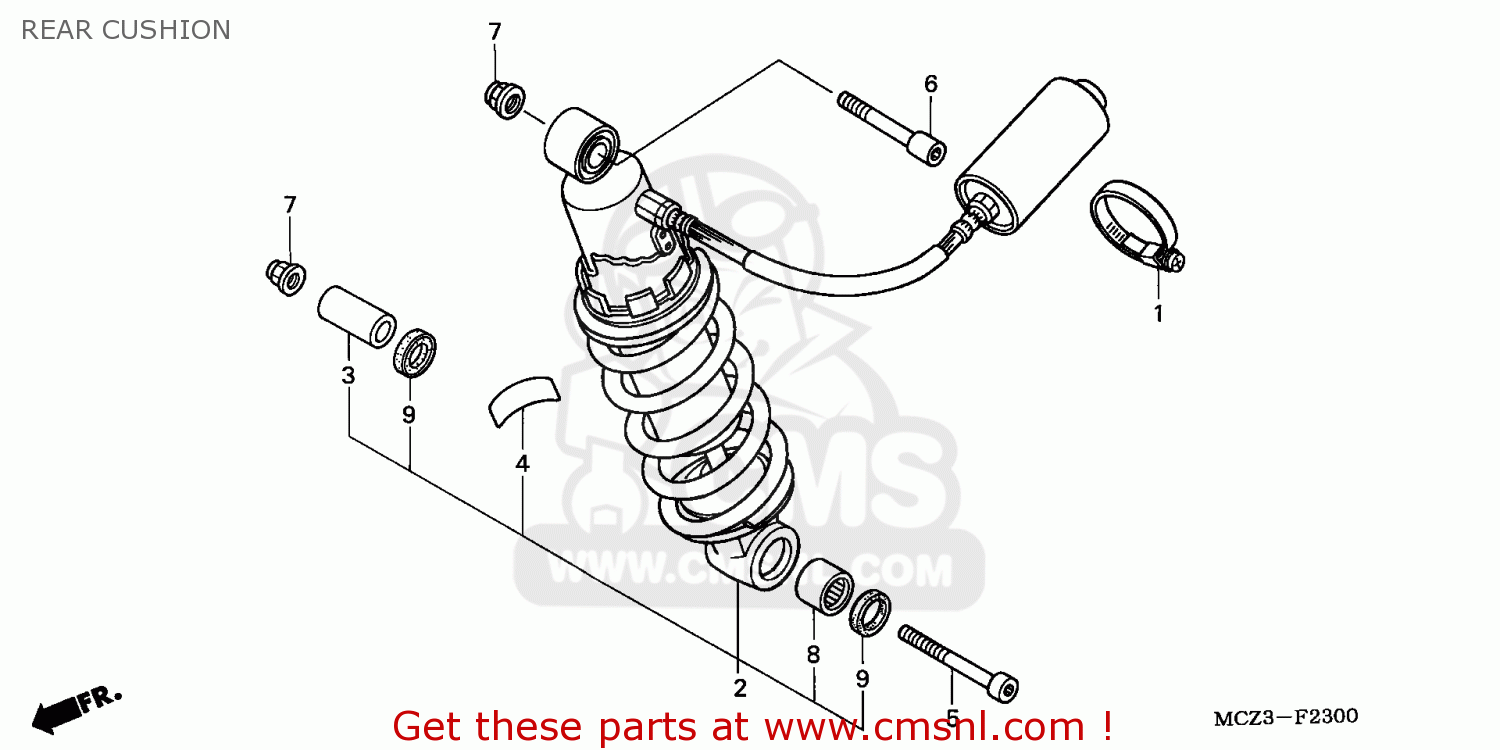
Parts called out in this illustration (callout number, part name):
1	BAND,SUB TANK
2	CUSHION ASSY,REAR
3	COLLAR,CUSH CONN
4	LABEL,RR DAMPER
5	BOLT,SOCKET 10X70
6	BOLT,SOCKET 10X48
7	NUT,U,FLANGE,10MM
8	NEEDLE BRG
9	DUST SEAL,17X24X5
